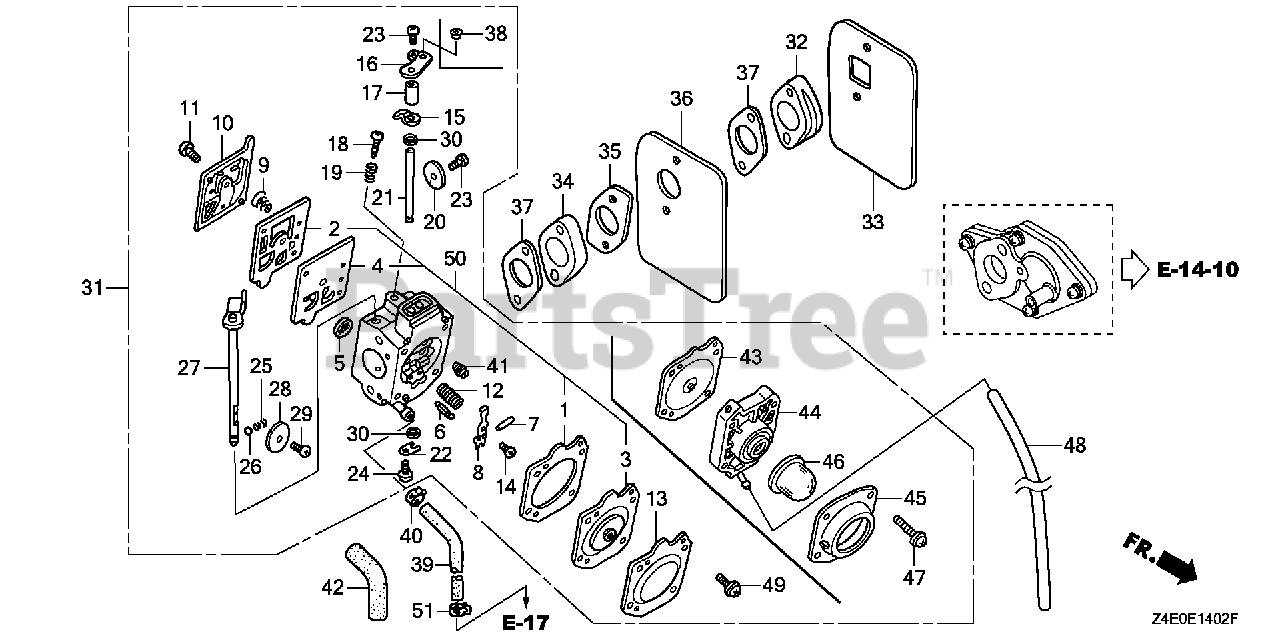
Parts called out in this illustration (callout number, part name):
1	GASKET, METERING DIAPHRAGM (CARBURETOR NO.)
2	GASKET, PUMP
4	DIAPHRAGM, PUMP
5	SCREEN, INLET
6	VALVE, INLET NEEDLE
7	PIN, METERING LEVER
8	LEVER, METERING
9	SPRING, PUMP
10	COVER, PUMP (CARBURETOR NO.)
12	SPRING (CARBURETOR NO.)
14	SCREW (CARBURETOR NO.)
15	STOPPER, THROTTLE LEVER
16	LEVER, THROTTLE (CARBURETOR NO.)
17	SPACER, THROTTLE LEVER
18	SCREW, IDLE ADJUSTING (CARBURETOR NO.)
20	VALVE, THROTTLE (CARBURETOR NO.)
21	VALVE, THROTTLE (CARBURETOR NO.)
21	SHAFT, THROTTLE (CARBURETOR NO.)
22	CLIP, THROTTLE SHAFT
23	SCREW, VALVE
24	SCREW ASSY.
27	SHAFT ASSY., CHOKE (CARBURETOR NO.)
28	VALVE, CHOKE
31	CARBURETOR ASSY. (HDA 278C)
32	INSULATOR, CARBURETOR
33	GASKET, INSULATOR
34	INSULATOR B, CARBURETOR
35	GASKET B, INSULATOR
36	PLATE, INSULATOR
37	GASKET, CARBURETOR
38	COLLAR, LEVER (CARBURETOR NO.)
39	HOSE, FUEL (4.2X330) (FKM)
40	CLAMP, TUBE (D8.5)
41	JET (#46) (CARBURETOR NO.)
41	JET (#48) (CARBURETOR NO.)
41	JET (#50) (CARBURETOR NO.)
41	JET (#52) (CARBURETOR NO.)
41	JET (#54) (CARBURETOR NO.)
42	BULK HOSE, VINYL (11X13X3000) (11X13X260)
43	DIAPHRAGM ASSY., METERING (CARBURETOR NO.)
44	BODY ASSY., AIR PURGE (CARBURETOR NO.)
45	COVER, PRIMER PUMP (CARBURETOR NO.)
46	PUMP, PRIMER (CARBURETOR NO.)
47	SCREW ASSY. (CARBURETOR NO.)
51	CLAMP, TUBE (D9.4)
51	CLAMP, TUBE (D8.5)
